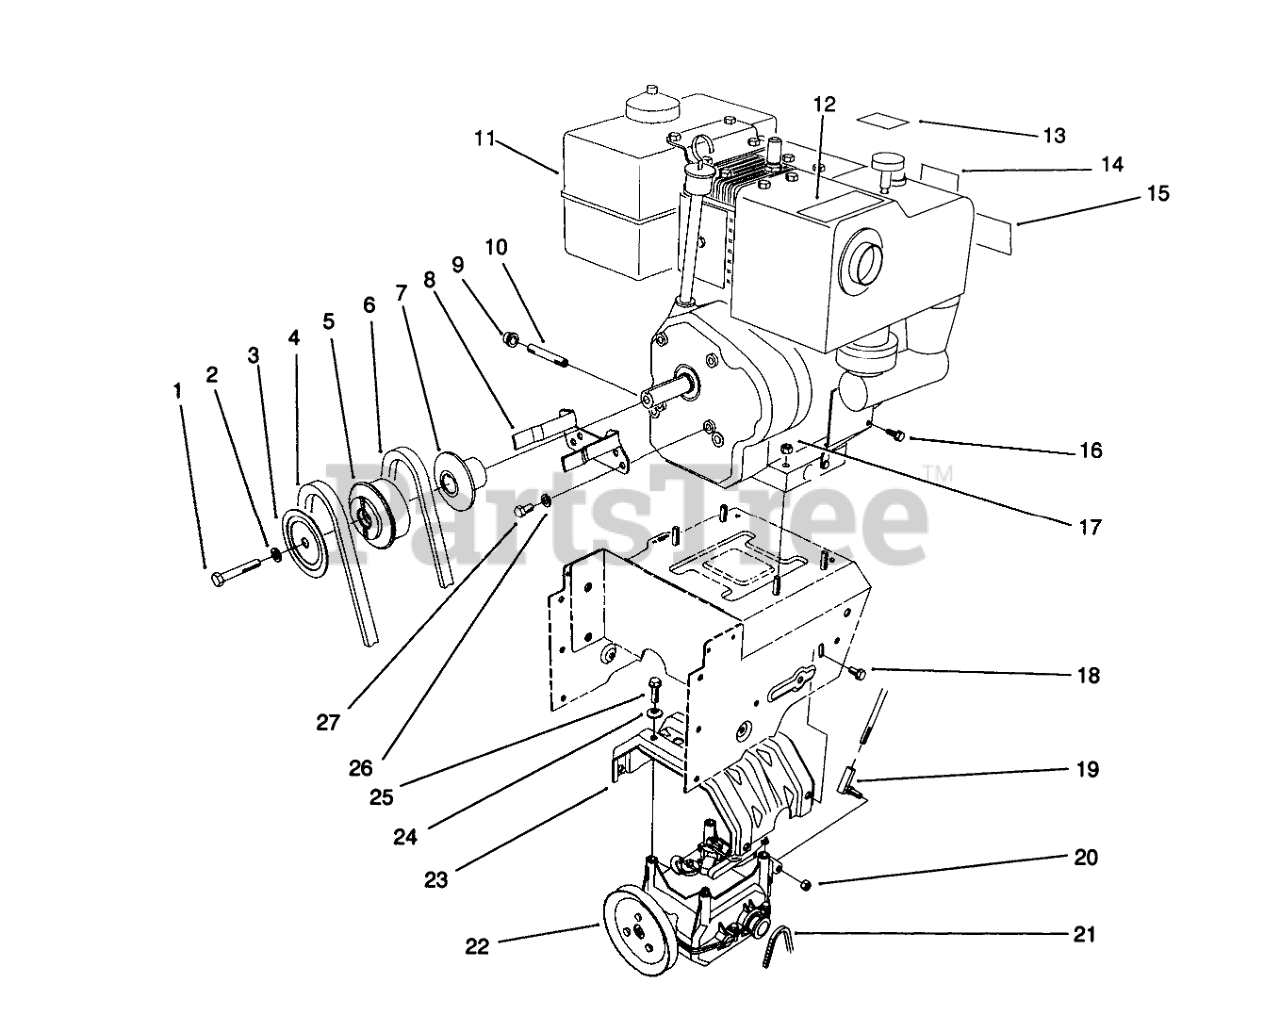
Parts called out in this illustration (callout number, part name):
1	SCREW-HH
2	WASHER-LOCK
3	SHEAVE-HALF, IMPELLER
4	V-BELT, IMPELLER
5	PULLEY-ENGINE, CENTER
6	V-BELT, TRACTION
7	SHEAVE-HALF, TRACTION
8	Guide-Belt
9	CAP-PIPE
10	NIPPLE-PIPE
12	DECAL-WARNING, HOT SURFACE
13	DECAL - THROTTLE, INT'L
14	DECAL - PRIMER, INT'L
15	DECAL - CHOKE
16	SCREW-HH
17	NUT-HF
18	SCREW-HHF
19	JOINT-BALL
20	NUT-LOCK, NI
21	CHAIN
22	TRACTION GEARCASE ASM
23	Frame-Transmission
24	WASHER-SPRING
25	SCREW-HWHTF
26	WASHER-LOCK
27	SCREW-HH
